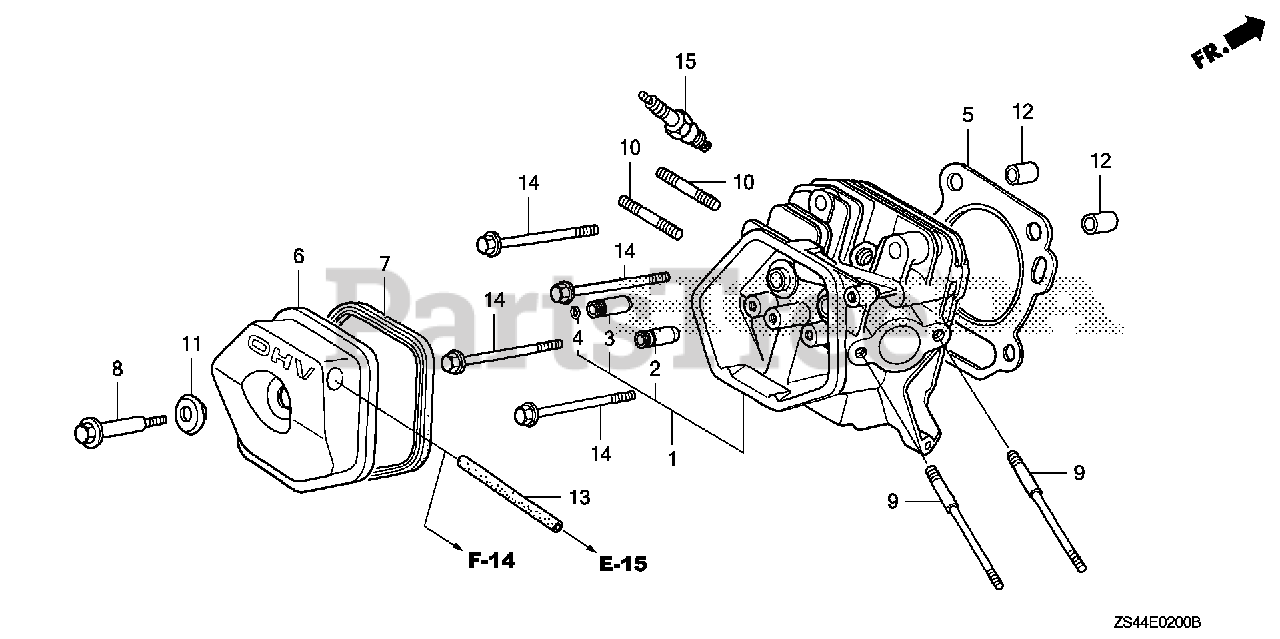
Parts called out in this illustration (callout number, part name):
1	CYLINDER HEAD
2	GUIDE, VALVE (OVER SIZE)
3	GUIDE, EX. VALVE (OVER SIZE)
4	CLIP, VALVE GUIDE
5	GASKET, CYLINDER HEAD
6	COVER, HEAD
7	GASKET, HEAD COVER
8	BOLT, HEAD COVER
9	BOLT, STUD (8X123)
10	BOLT, STUD (8X32)
11	WASHER, HEAD COVER
12	PIN, DOWEL (12X20)
13	BULK HOSE, VACUUM (11X1000) (11X100)
14	BOLT, FLANGE (10X80)
15	SPARK PLUG (W16EPR-U) (DENSO)
